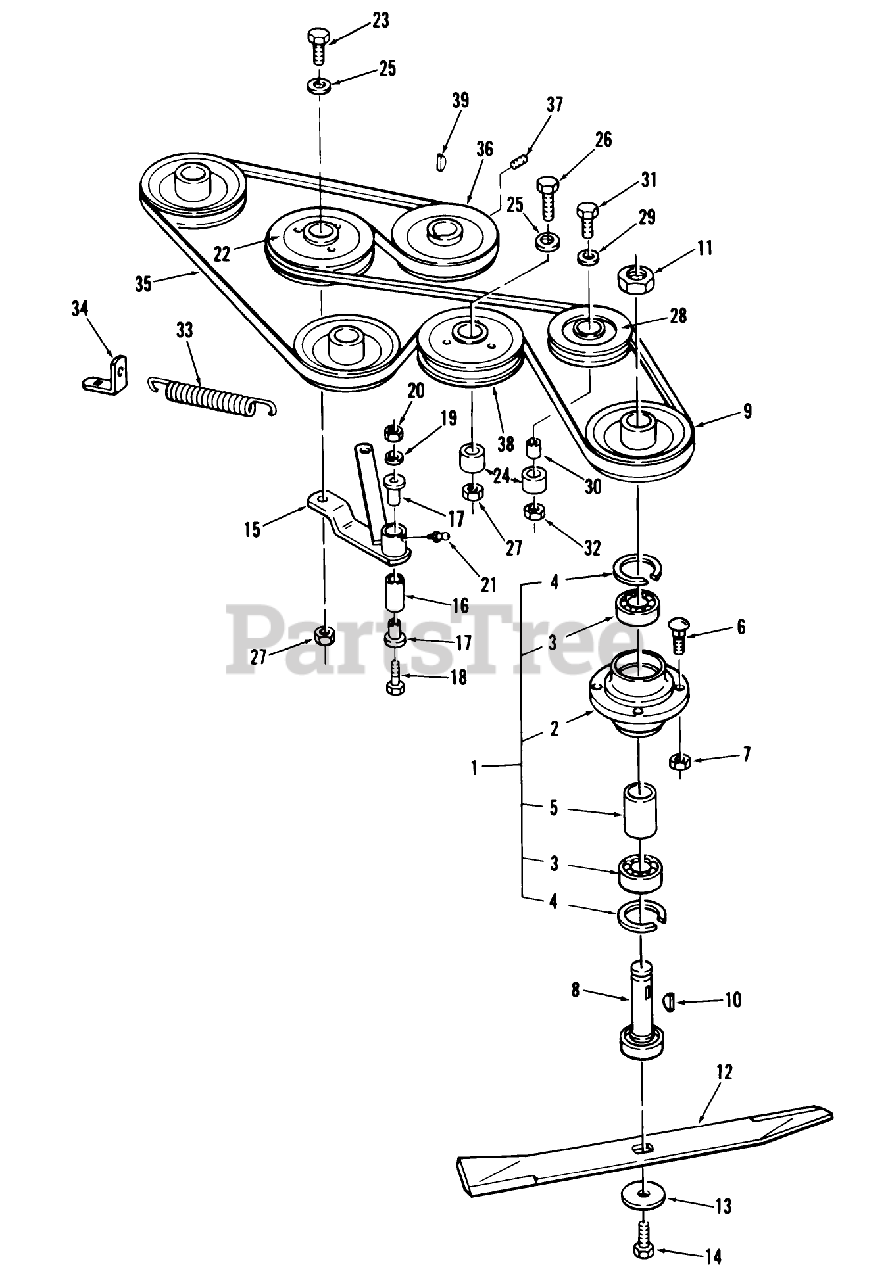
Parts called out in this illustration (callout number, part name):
17	BUSHING
33	SPRING-EXTENSION
35	V-BELT, DECK DR.
